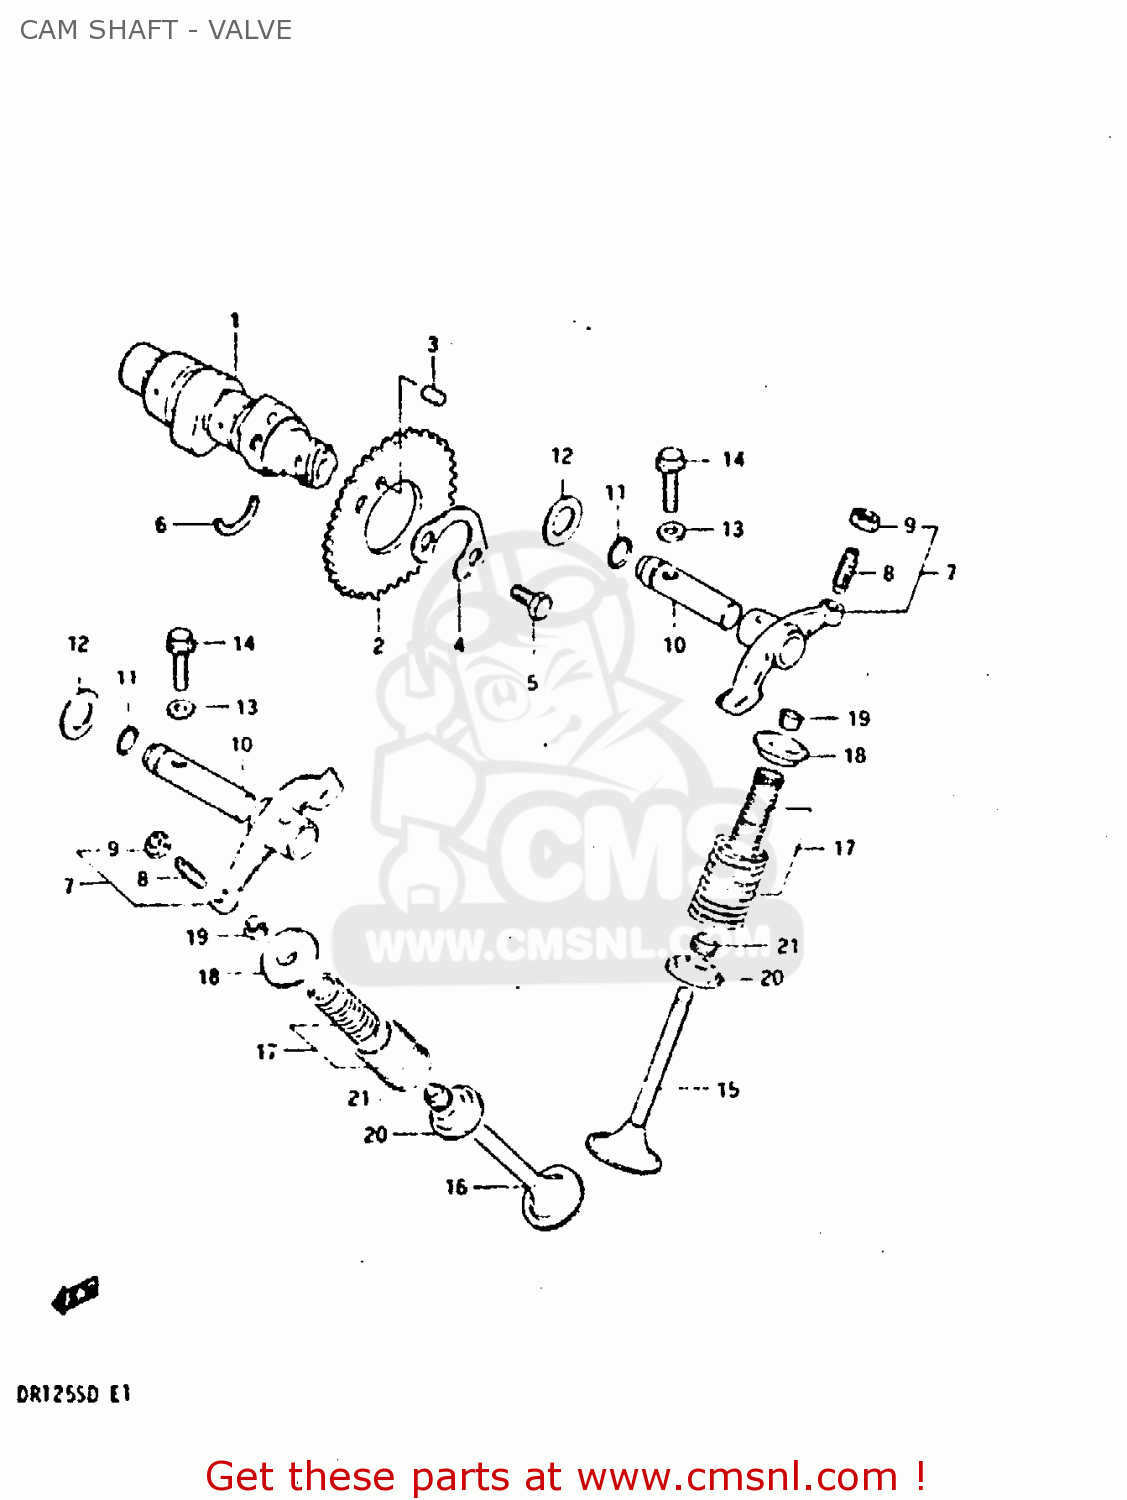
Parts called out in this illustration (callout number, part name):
1	CAMSHAFT
2	SPROCKET,CAMSHAFT
3	PIN(5X8)
4	WASHER,SPROCKET
5	BOLT(6X10.5)
6	C RING
7	ARM,VALVE ROCKER
8	SCREW,TAPPET ADJUSTING
9	NUT,ADJUSTING SCREW
10	SHAFT,VALVE ROCKER
11	O-RING
12	WASHER
13	GASKET(6.2X11X1).2 (NAS)
14	BOLT
15	VALVE,INTAKE
16	VALVE,EXHAUST
17	SPRING SET,VALVE
18	RETAINER,VALVE SPRING
19	COTTER VALVE
20	SEAT,VALVE SPRING
21	OIL SEAL
